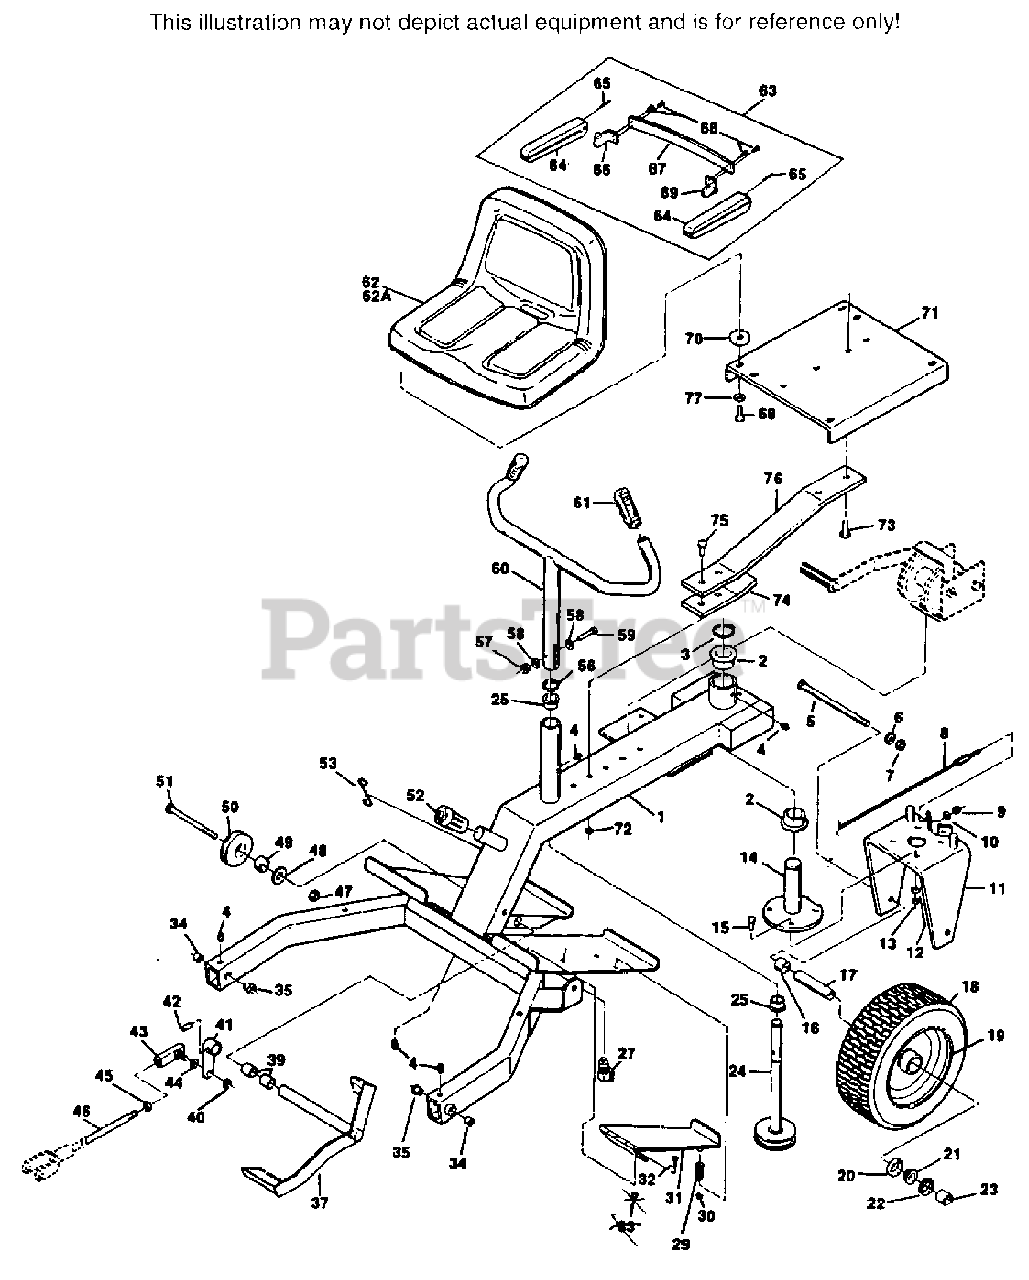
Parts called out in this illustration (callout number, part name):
1	STEERING FRAME(INCL. BUSHINGS & GREASE
2	BRONZE BUSHING
3	RETAINING RING, 1-1/8 EXTERNAL
4	GREASE FITTING
6	LOCK WASHER, 5/8 SPRING
8	CABLE, STEERING
9	HEX NUT, 1/4-28 LOCK
11	REAR WHEEL YOKE
12	LOCK WASHER, 3/8 SPRING
14	REAR WHEEL PIVOT
16	SPACER, REAR WHEEL
17	SLEEVE, REAR WHEEL
18	REAR WHEEL ASSY.(INCL. 19,20,21,22)
19	RIM ONLY
20	BEARING CUP
21	BEARING CONE
22	SEAL, GREASE
23	SPACER, REAR WHEEL, SHORT
24	STEERING SHAFT
25	BRONZE BUSHING
27	SWITCH, FOOT SAFETY
29	SPRING, FOOT SAFETY SWITCH
30	HEX, NUT, ELASTIC STOP LOCK, 1/4-20
31	PEDAL, FOOT SAFETY SWITCH
34	BRONZE BUSHING
35	BRONZE BUSHING
37	FOOT PEDAL
41	FOOT PEDAL ARM
42	PIN, DRIVE LOCK, 3/16 X 1-1/4
43	BALL JOINT
46	CONTROL ROD
47	HEX NUT, ELASTIC STOP NUT, 1/2-13
49	BRONZE BUSHING
50	PULLEY, WINCH CABLE
52	BUMPER STOP COVER
53	RETAINER, WINCH CABLE
56	RETAINING RING, 7/8 EXTERNAL
57	HEX NUT, 5/16-18 CENTER LOCK
58	FLAT WASHER, 3/8 X 7/8 X 13 GA.
60	STEERING HANDLE(INCL. 61)
61	GRIP
62	SEAT ASSY.(INCL. 62A & 63)
62A	SEAT ONLY
63	ARM REST KIT(INC. 64,65,66,67,68,69)
64	ARM REST
65	SETSCREW, 3/8-16 X 3/4 FLAT POINT
67	BACK STRAP
69	MOUNTING BRACKET, LH
70	FLAT WASHER, 13/32 X 1-1/2 X 7 GA.
71	SEAT PLATE
74	REINFORCEMENT, SEAT SPRING
76	SEAT SPRING
77	LOCK WASHER, 5/16 SPRING
